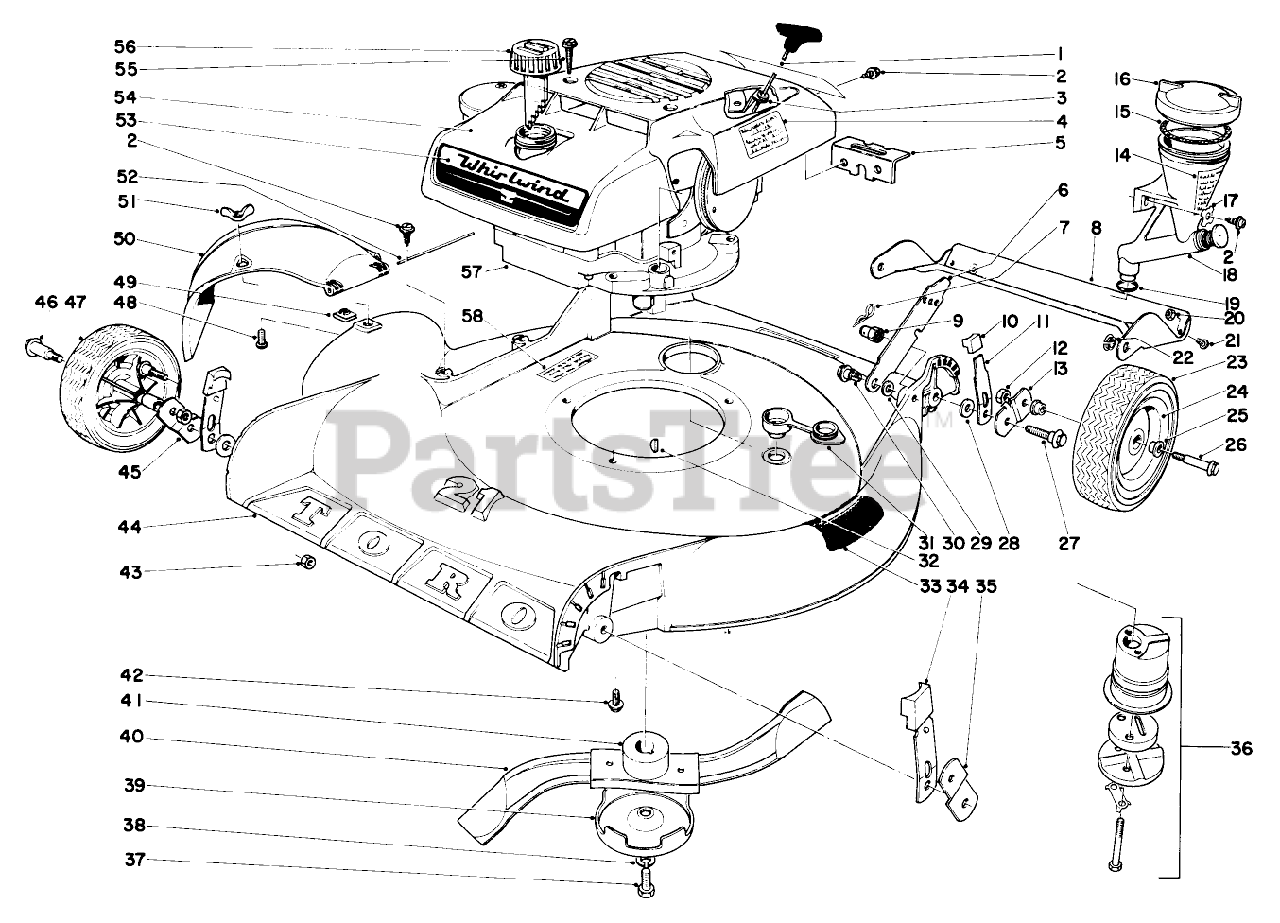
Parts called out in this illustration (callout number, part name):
1	Decal
3	Bracket,Recoil
4	Decal,Start
5	Bracket
7	PIN-COTTER, HAIR
8	Safety Shield-Rear
13	Pivot Arm
14	Decal, Reservoir
16	Cap, Reservoir (Incl. Ref. 15)
17	Washer
19	O-RING
20	NUT-JAM
22	Nyliner
26	Wheel Bolt
28	WASHER-PIVOT
29	SPACER
30	SCREW-SHOULDER
32	KEY-WOODRUFF
34	ARM KNOB
38	WASHER-LOCK
41	BLADE RETAINER WA
44	Housing
49	NUT-SPEED
51	NUT-WING SPECL
53	Decal
54	Shroud
55	SCREW-HWH
57	Engine
